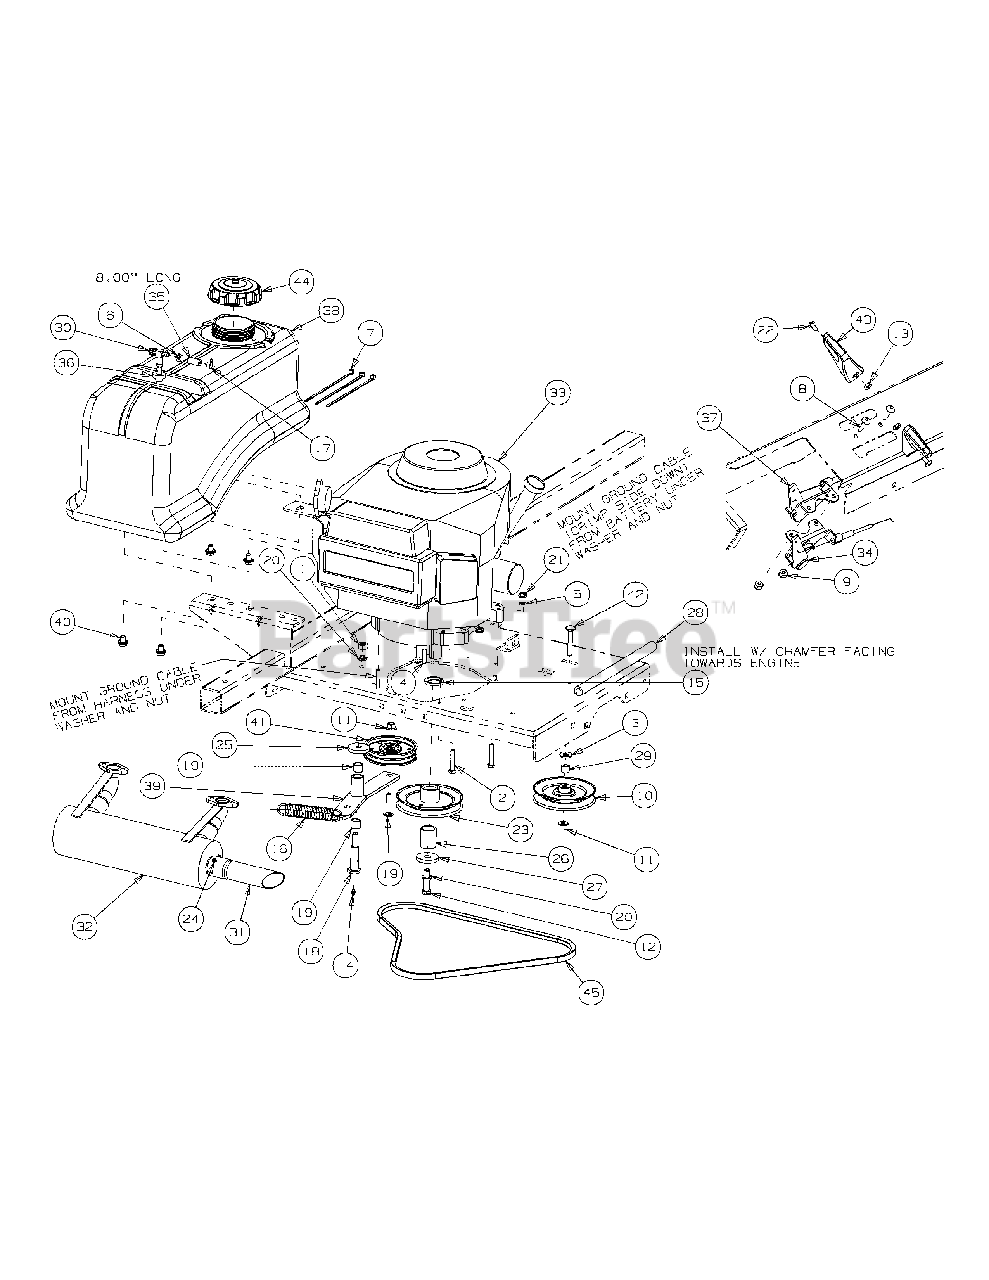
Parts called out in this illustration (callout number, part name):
1	Nut Hex, 7/16-14
2	HHCS, 5/16-18, 1-3/4
3	Flat Washer, 3/8
4	Key, 1/4 x 1/4 x 1.125
5	Flat Washer, 5/16
6	Clamp, Union
7	Cable Tie
8	Screw, Machine, 10-32 x 3/4
9	Nut, Lock, Nylon Insert, #10-32
10	Idler Pulley
11	Nut, Hex, Flange Lock, 3/8-16
12	Capscrew, 7/16-20 x 1.75
13	Nut, Washer, With Star, 8-32
14	Fitting, Grease, 1/4-28 x 3/16
15	Spacer, Engine Pulley
16	Spring, Extension, 1.0 OD x 5.0"
17	Hose Clamp, SAE #4: 1/4-5/8, SS
18	Shoulder Screw, 7/16-14
19	Bolt, Carriage, 3/8-16 x 1.75
20	Washer, Lock, 7/16
21	Nut Lock, Hex Flange 5/16-18
22	Machine Screw, 8-32, .375
23	Pulley, Transmission Drive
24	Screw, 8-32 x 0.375
25	Washer, Flat, 7/16 ID x 1.75 OD
26	Spacer, 1.015 ID x 1.25 OD x 1.50
27	Flat Washer, 7/16 ID x 1.75 OD
28	Oil Drain Extension Hose
29	Spacer, .625 OD x .385 ID x 1/2
30	Fuel Fitting
31	Tube, Exhaust Selxsys Muffler
32	Muffler Accessory Kawasaki
33	Engine, 17HP Kawasaki
34	Cable, Control 39.0 Throttle
35	Hose, 1/4" Fuel Line
36	Fuel Tank Grommet
37	Choke Control Cable,
38	Fuel Tank
39	Engine Idler Arm Assembly Includes:
39	Bearing
40	HHCS, 3/8-16 x .500, Flange Whiz
41	Flat Pulley with Flanges
42	Carriage Bolt, 3/8-16 x 2.25
43	Knob, Throttle Control
44	Fuel Cap, 3.5
45	Belt, Pump Drive
